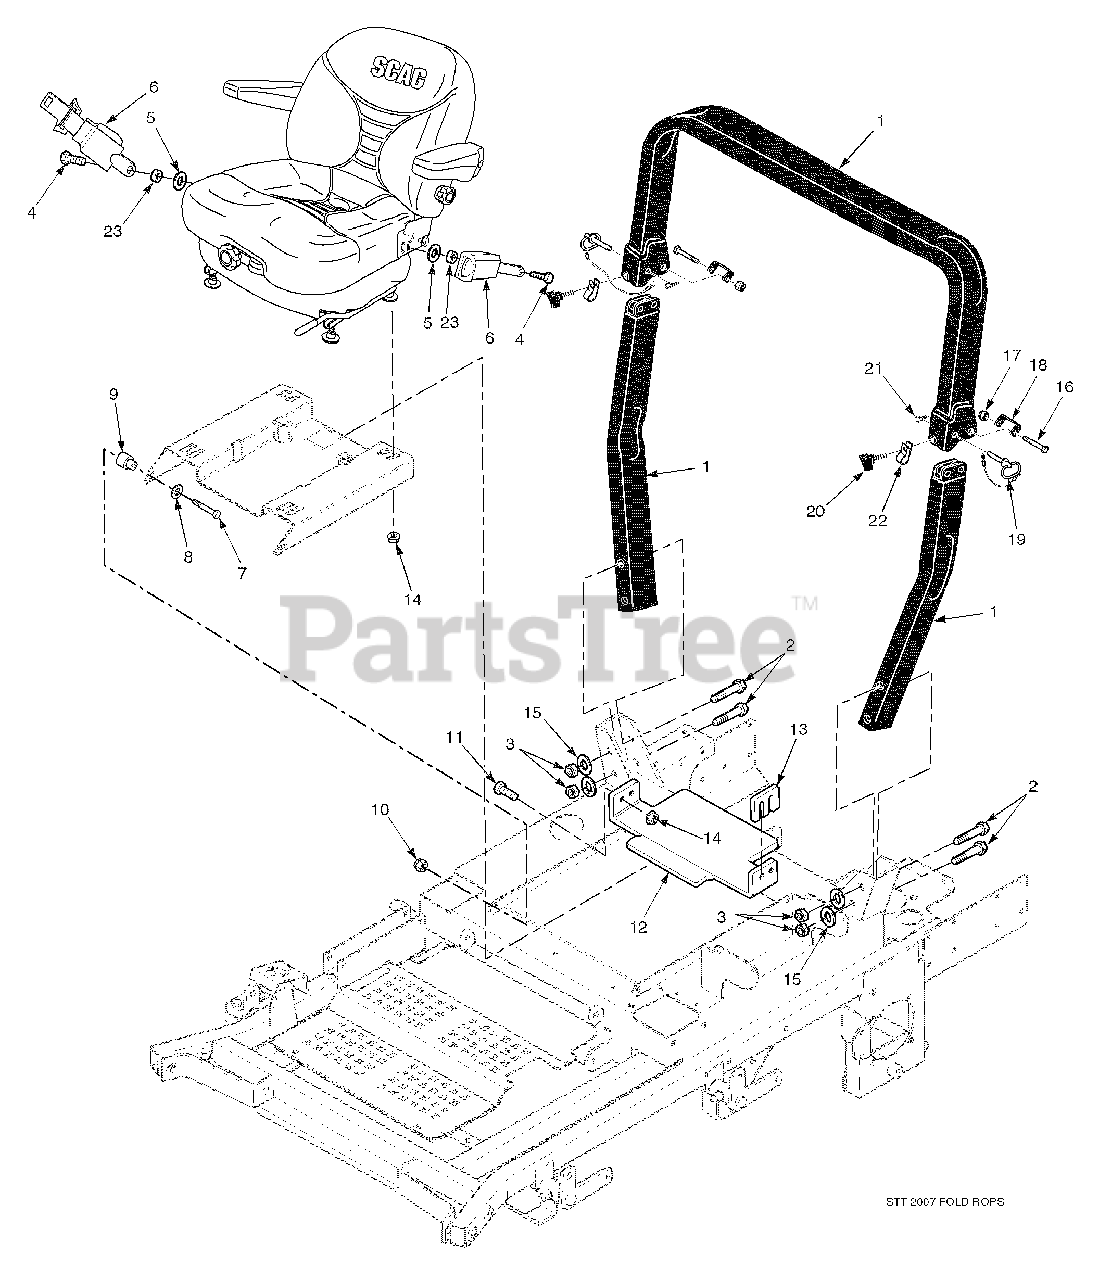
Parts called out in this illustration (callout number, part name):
1	STT, ROPS Accessory
2	Bolt, Hex Head 1/2-13 x 4-1/2"
3	Nut, Center Lock 1/2-13
4	Bolt, Hex Head 7/16-20 x 1"
5	Flatwasher, 7/16-.500 x 1.25 x .083
6	Retractable Seat Belt
7	Bolt, Hex Head 3/8-16 x 2"
8	Flatwasher, 3/8-.391 x .938 x .105
9	Sleeve, Seat Base Mounting
10	Nut, Elastic Stop 3/8-16
11	Bolt, Hex Head 5/16-18 x 1"
12	Bracket, Seat Hold Down with Decal
13	Spacer, Seat Hold Down
14	Nut, Serrated Flange 5/16-18
15	Flatwasher, 1/2-.562 x 1.375 x .109
16	Bolt, Hex Head 1/2-13 x 3-1/2"
17	Nut, Center Lock 1/2-13
18	Bracket, Stop
19	Pin
20	Thumb Screw, 5/16-18 NC x 3/4"
21	Hair Pin, Cotter
22	Clamp
23	Spacer
